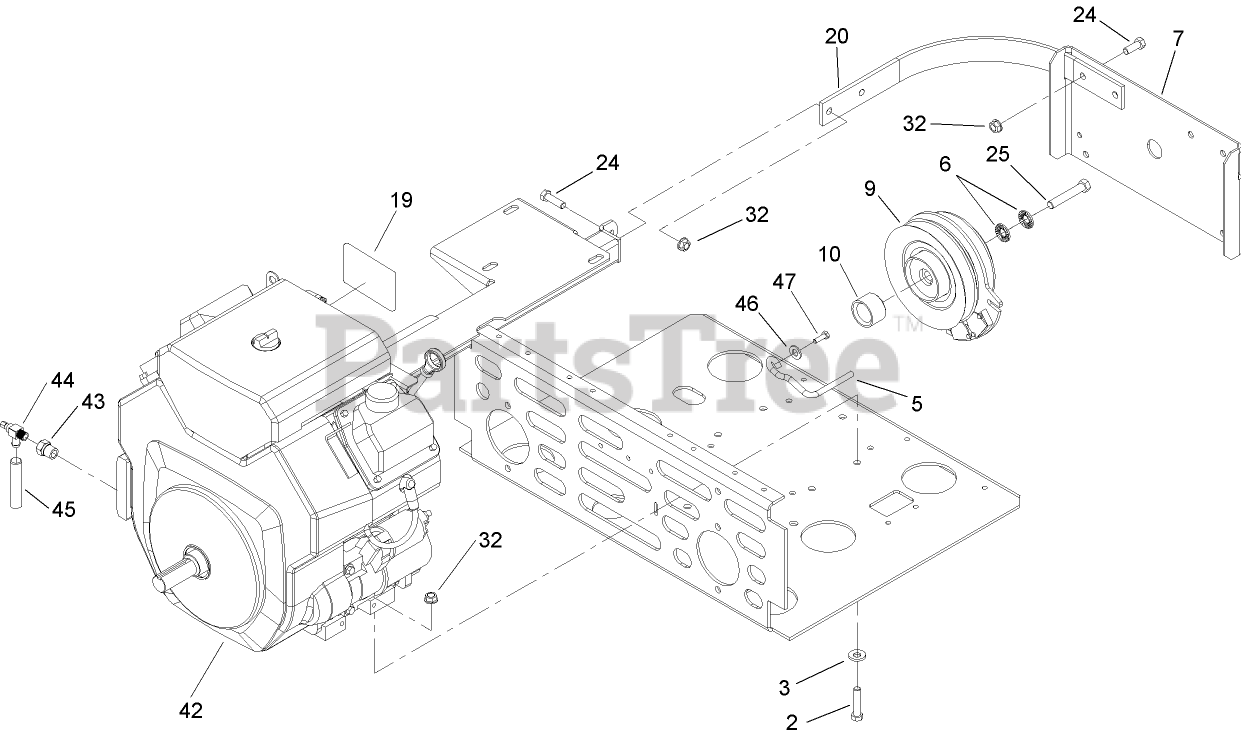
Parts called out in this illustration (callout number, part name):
2	SCREW-HH
3	WASHER-BELLEVILLE
5	ROD-BELT
6	WASHER-SPRING
7	GUARD-CLUTCH
9	Clutch
10	SPACER-CLUTCH
20	BRACKET-GUARD, TOP
24	SCREW-HH
25	SCREW-HH
32	NUT-HHF, WHIZ
43	Adapter
44	Valve-Drain, Oil
45	HOSE-DRAIN, OIL
46	WASHER-FLAT
47	SCREW
